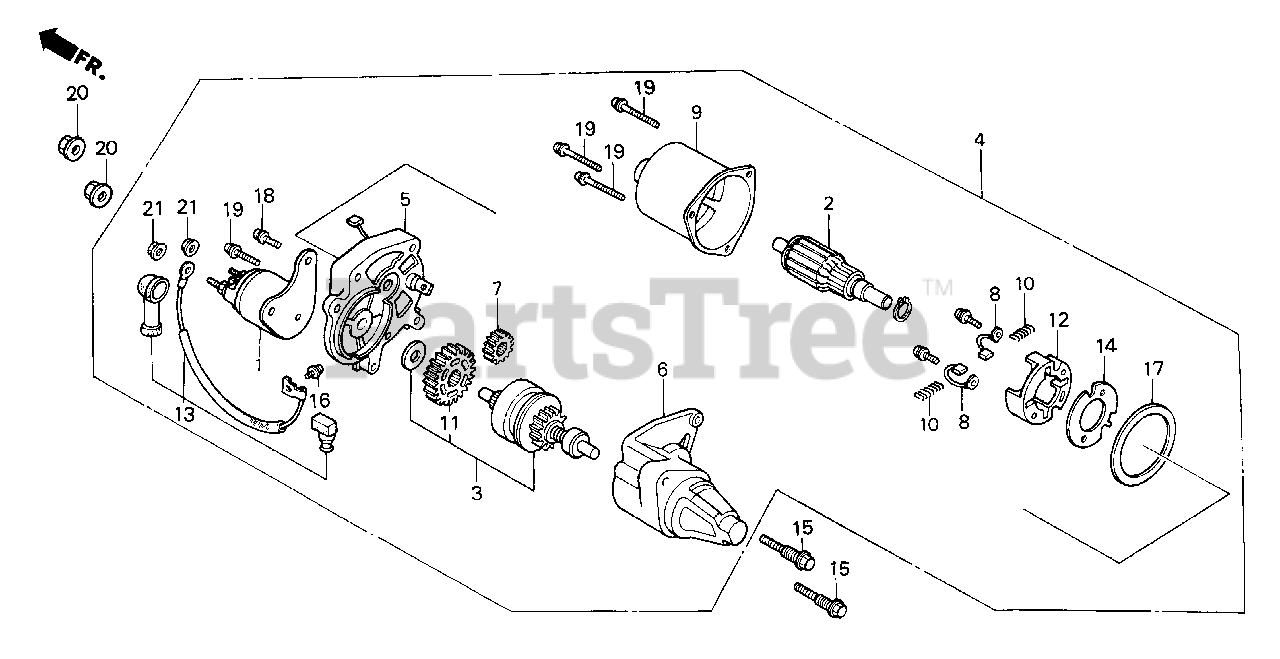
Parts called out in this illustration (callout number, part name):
1	CONTACTOR ASSY.
3	CLUTCH, OVERRUNNING
4	MOTOR ASSY., STARTER
5	BRACKET, CENTER
6	BRACKET, FR.
7	GEAR, DRIVE PINION
10	SPRING, BRUSH RETURN
11	GEAR, REDUCTION
12	HOLDER, BRUSH
13	WIRE, WATER COVER
15	BOLT, STARTER MOTOR
16	SCREW-WASHER (4X6)
18	SCREW-WASHER (5X14)
19	SCREW-WASHER (5X3)
20	NUT, FLANGE (8MM)
21	NUT-WASHER (6MM)
